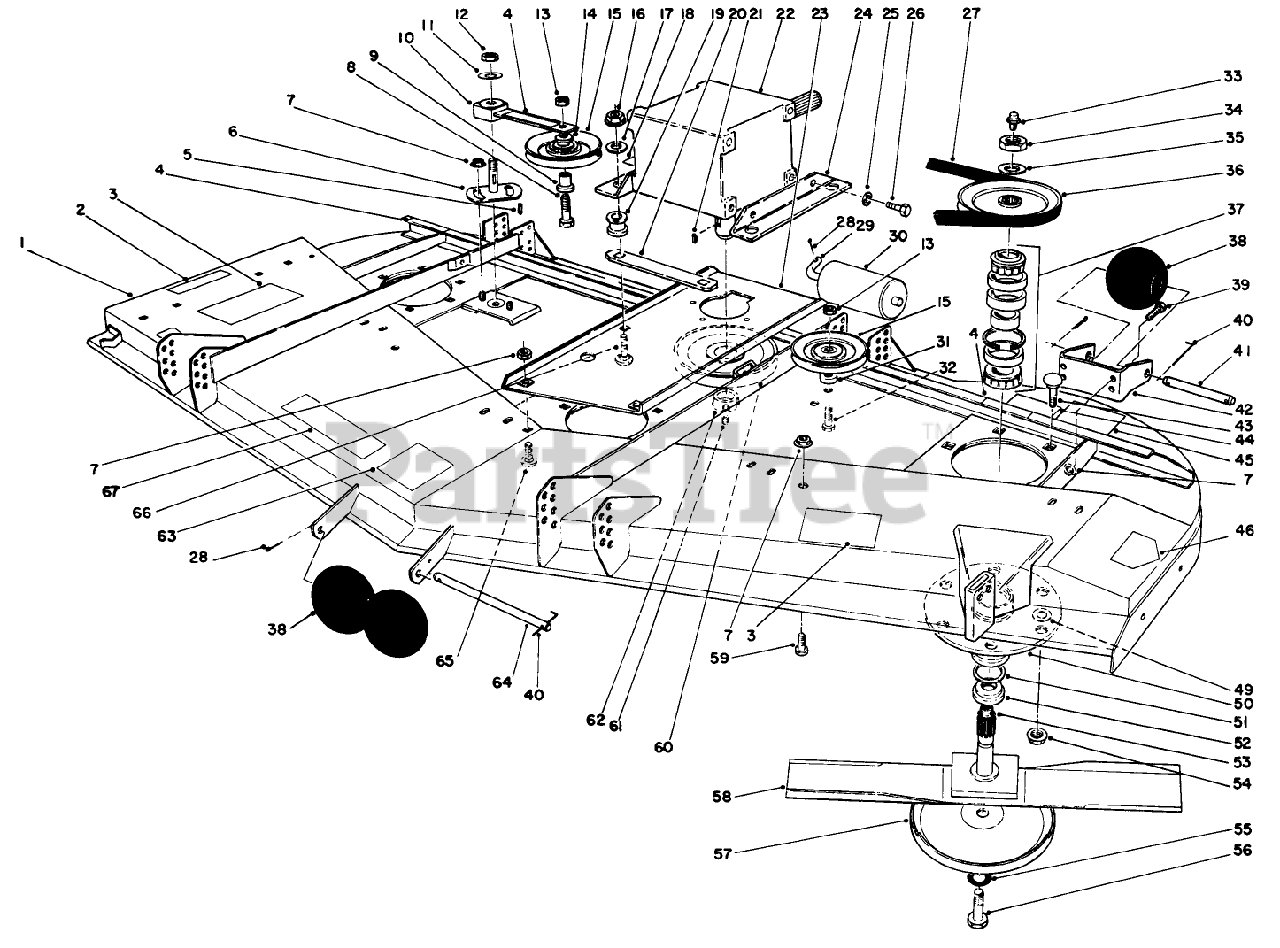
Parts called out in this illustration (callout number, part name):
1	Cuffing Deck
2	DECAL-DANGER
3	DECAL-DANGER, THROWN OBJECT
4	DECAL-DANGER
5	KEY-SQUARE
6	PLATE-IDLER
7	NUT-HHF, WHIZ
8	SCREW-HH
9	BUSHING-PULLEY
10	IDLER ARM ASM
11	WASHER-FLAT
12	NUT-LOCK, NI
13	NUT-HEX
14	WASHER-FLAT
15	PULLEY-IDLER
16	NUT-LOCK, SIDE
17	WASHER
18	DECAL-OIL
19	MOUNT
20	Cover-Gear Box
21	KEY-WOODRUFF
22	Gearbox
23	Base-Gearbox
24	Bracket-Gearbox
25	WASHER-LOCK
26	SCREW-HH
27	V-BELT
28	PIN-COTTER
29	SHAFT-ROLLER, REAR
30	ROLLER-DECK
31	SPACER
32	SCREW-HH
33	FITTING-GREASE
34	NUT-HEX
35	WASHER
36	PULLEY AND HUB ASM
37	BEARING ASM
38	ROLLER
39	SCREW-HH
40	PIN-SPECIAL
41	SHAFT-ROLLER
42	Bracket-Roller
43	SCREW-CARR
44	DECAL-TORQUE
45	DECAL-WARNING
46	DECAL-DANGER
49	WASHER-FLAT
50	HOUSING-SPINDLE
51	SEAL-OIL
52	SPACER
53	SHAFT
54	NUT-HF
55	WASHER
56	SCREW-BLADE
57	CUP-SCALP, ANTI
58	Blade
59	SCREW-HH
60	PULLEY
61	SCREW-SET, HSH
62	Bushing-Taper Lock (Incl. Ref. #61)
63	DECAL
64	SHAFT-ROLLER
65	SCREW-CARR
66	SCREW-CARR
67	DECAL-PROLINE
